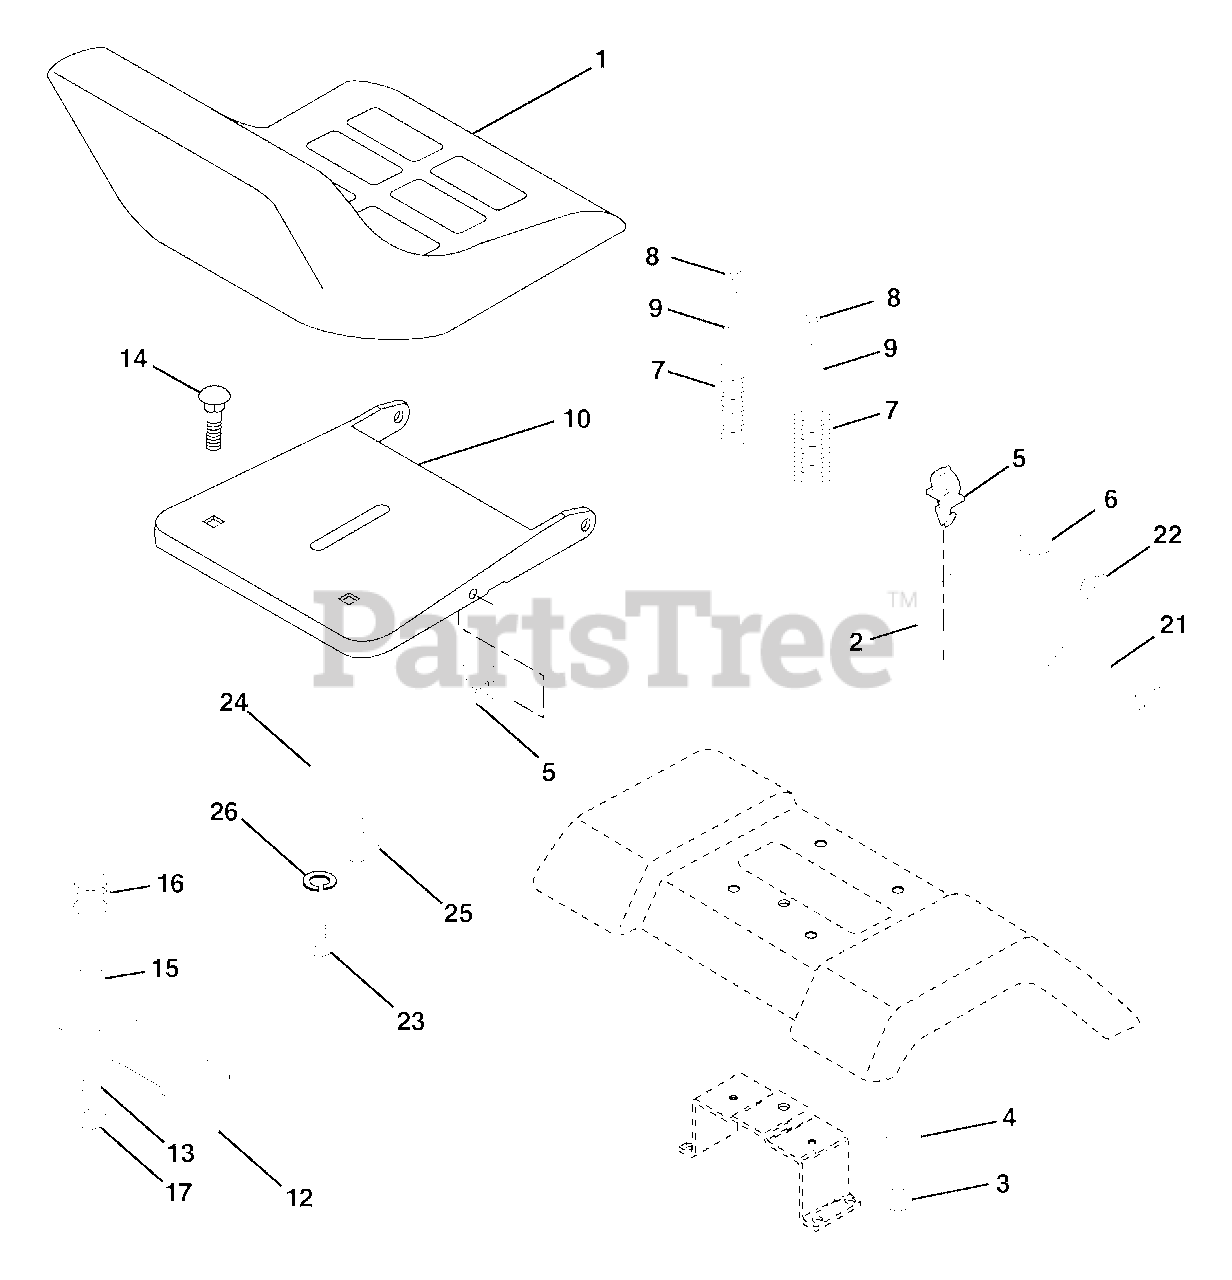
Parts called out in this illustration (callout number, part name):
1	Seat
2	Bracket Seat Pivot
3	Bolt Hex 3/8 - 16 x 1
4	Washer 13/32 x 1 x 10 Ga.
5	Clip Push-In Hinged
6	Nut Lock Hex w/Ins 3/8 - 16
7	Spring Seat Cprsn 2 250 Blk Zi
8	Screw 3/8-16 x 1.5
9	Washer 13/32 x 1 x 14 Ga.
10	Pan Pnt Seat (Blk)
12	Bracket Pnt Mounting Switch
13	Bushing Snap Blk Nyl
14	Bolt Rdhd Sht Nk 1/4 - 20 x 1-1/2
15	Spacer Split .28 x .96
16	Spring Cprsn
17	Nut Lock 1/4 Lge Flg
21	Bolt Shoulder 5/16-18 unc-2A
22	Nut Lock Hex w/Ins 5/16 - 18
23	Bolt Hex
24	Washer 17/32 x 1-3/16 x 12 Ga.
25	Bolt Shoulder 5/16-18 x .62
26	Washer Lock Hvy Hlcl Spr 1/2
